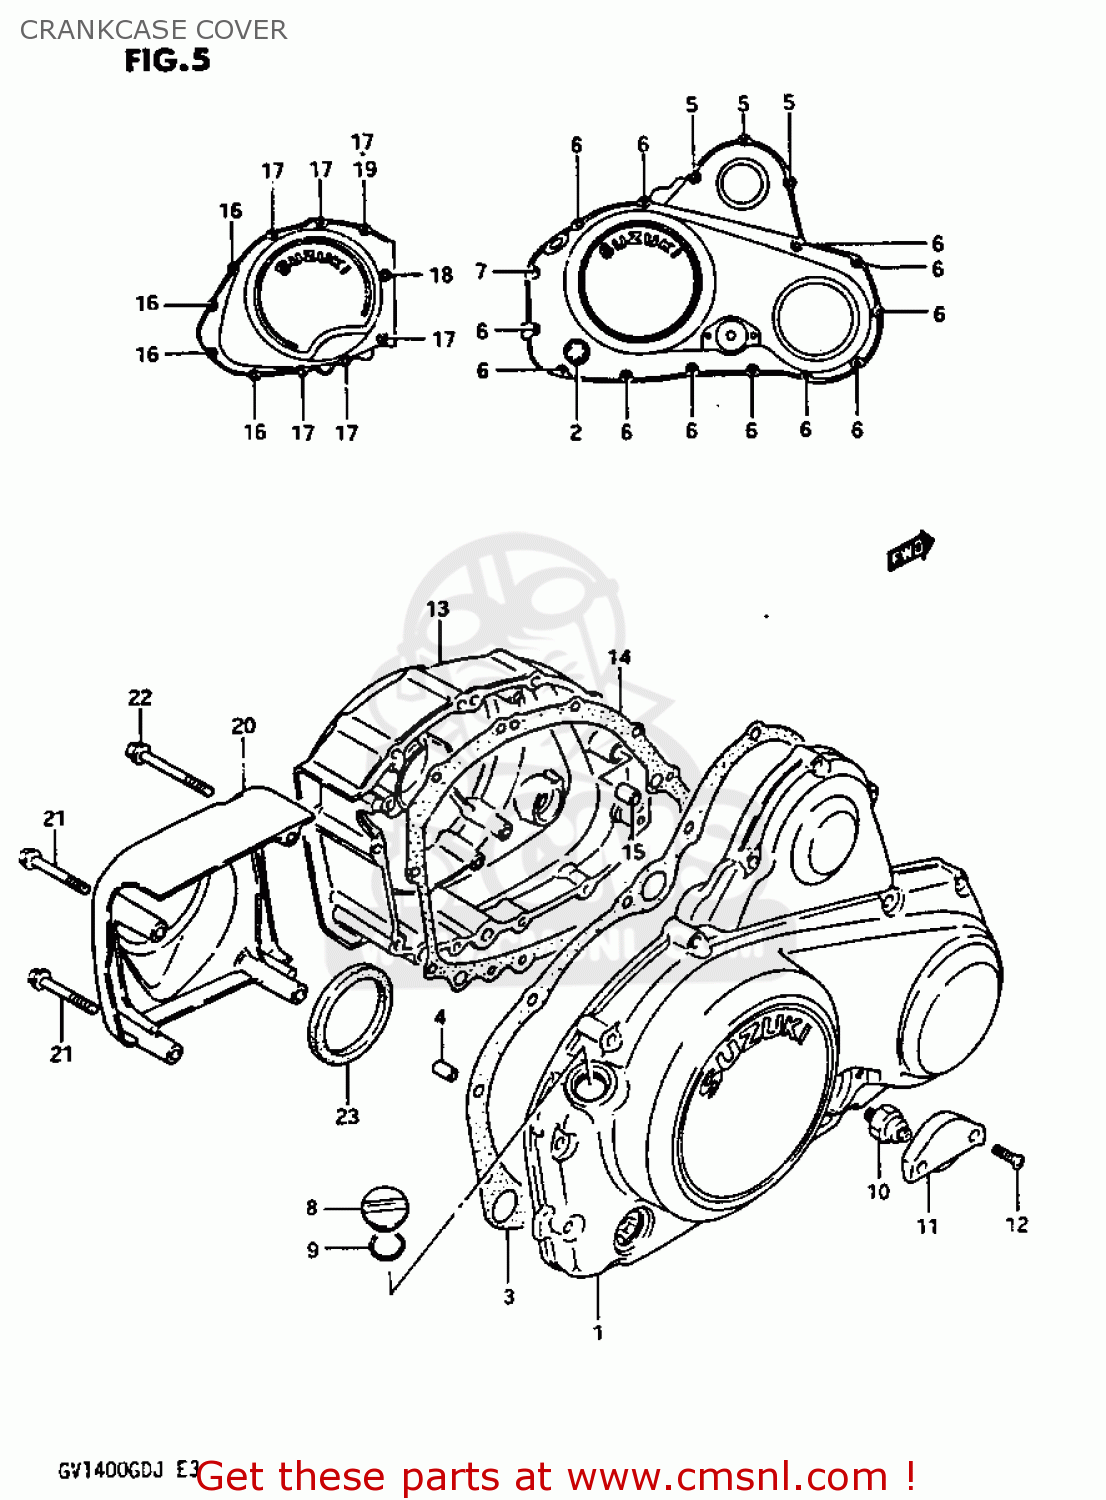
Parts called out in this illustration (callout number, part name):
1	COVER,CLUTCH
2	LENS,OIL LEVEL CHECK
3	GASKET,CLUTCH COVER (NAS)
4	PIN
5	BOLT
6	BOLT
7	BOLT
8	PLUG(20X10)
9	O RING(D:3.1,ID:16.8)
10	SWITCH ASSEMBLY,OIL PRESSURE
11	CAP,OIL PRESSURE SWITCH
12	SCREW (L:20)(SUS)
13	COVER
14	GASKET,GENERATOR COVER (NAS)
15	PIN (11X20)(SUS)
16	BOLT
17	BOLT
18	BOLT
19	GASKET(5.8X13X1.2) (NAS)
20	COVER,SPROCKET
21	BOLT
22	BOLT
23	DAMPER,SECONDARY COVER
